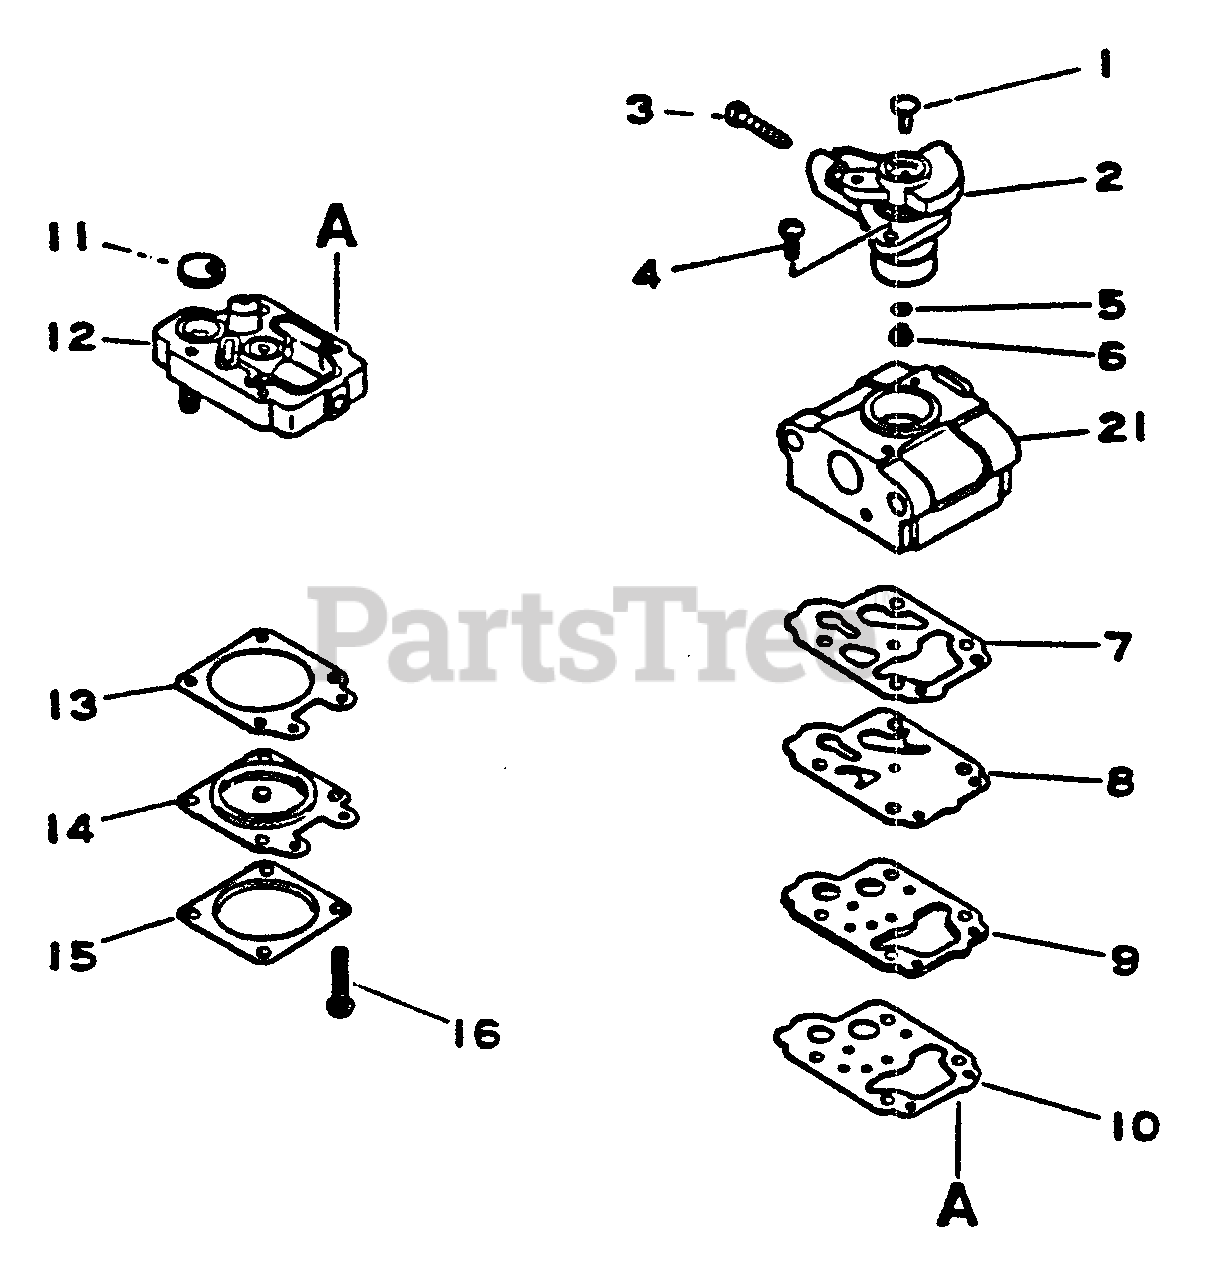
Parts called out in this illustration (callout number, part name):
1	PLUG, WELCH
2	VALVE, THROTTLE
3	SCREW, IDLE ADJUST
5	O-RING
6	JET
7	GASKET, PUMP
8	DIAPHRAGM, PUMP
9	PLATE, PUMP
10	GASKET, PLATE
11	STRAINER
12	PUMP BODY ASSY
13	GASKET, DIAPHRAGM
14	DIAPHRAGM, METERING
15	COVER, METERING
16	O-RING - 15
16	GASKET, INTAKE
